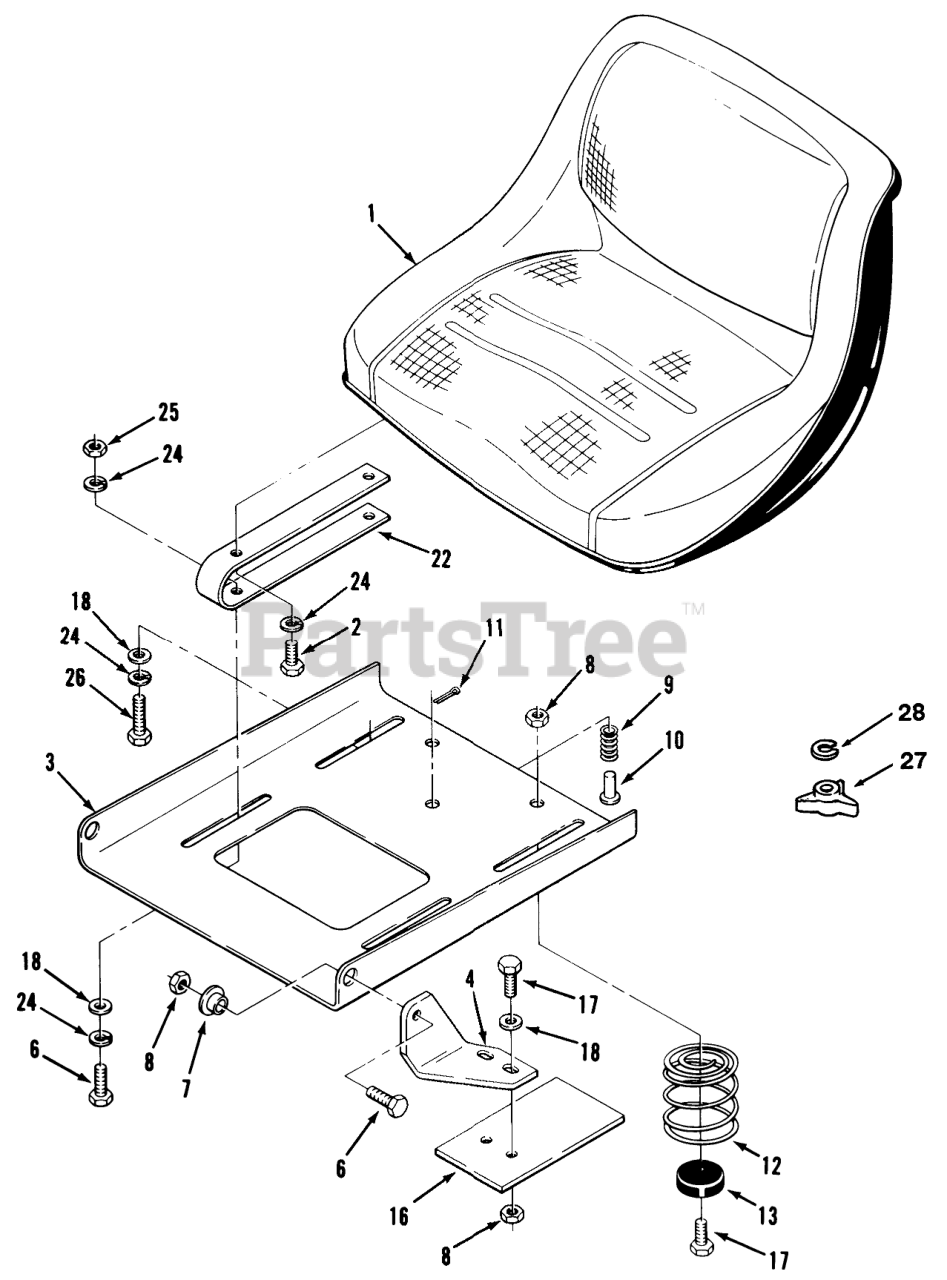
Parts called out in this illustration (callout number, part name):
1	Seat
2	Bolt
3	PLATE-SEAT PIVOT B
4	Bracket-Pivot RH
6	HHCS
7	BUSHING
8	Nut
9	SPRING-SEAT SWITCH
11	Cotter Pin
12	SPRING
13	BUMPER
16	PLATE R
17	Bolt
18	WASHER 5/16 SAE
22	SPRING-SEAT B
24	Lockwasher
25	Nut
26	Bolt
27	THREE-PRONG KNOB
28	LOCKWASHER INT EXT
